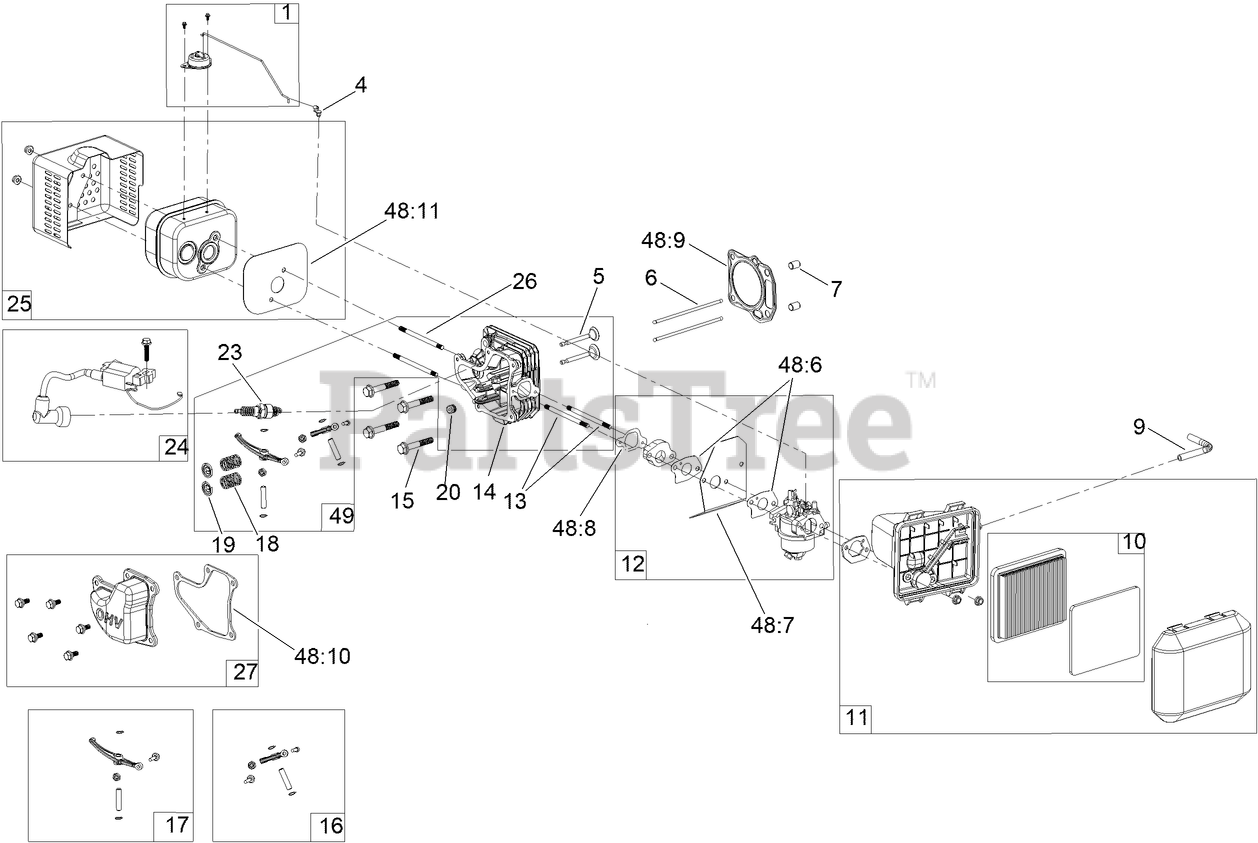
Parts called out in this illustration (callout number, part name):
1	THERMAL CONTROL KIT
4	LOCK-THROTTLE
5	VALVE SET
6	ROD-PUSH
7	PIN-DOWEL
9	TUBE-BREATHER
10	AIR FILTER AND PREFILTER KIT
11	AIR CLEANER ASM KIT
12	CARB REPLACEMENT KIT
13	STUD-INTAKE
14	HEAD-CYLINDER
15	BOLT-FLANGE
16	INTAKE ROCKER ARM ASM
17	EXHAUST ROCKER ARM ASM
18	SPRING-VALVE
19	RETAINER-VALVE, SPRING
20	SEAL-STEM, VALVE
23	SPARK PLUG
24	IGNITION ASM
25	MUFFLER AND SHIELD KIT
26	STUD-EXHAUST
27	VALVE COVER KIT
48:6	GASKET-CARBURETOR
48:7	INSULATOR-CARBURETOR
48:8	GASKET-INTAKE
48:9	GASKET-HEAD
48:10	GASKET-VALVE COVER
48:11	GASKET-EXHAUST
